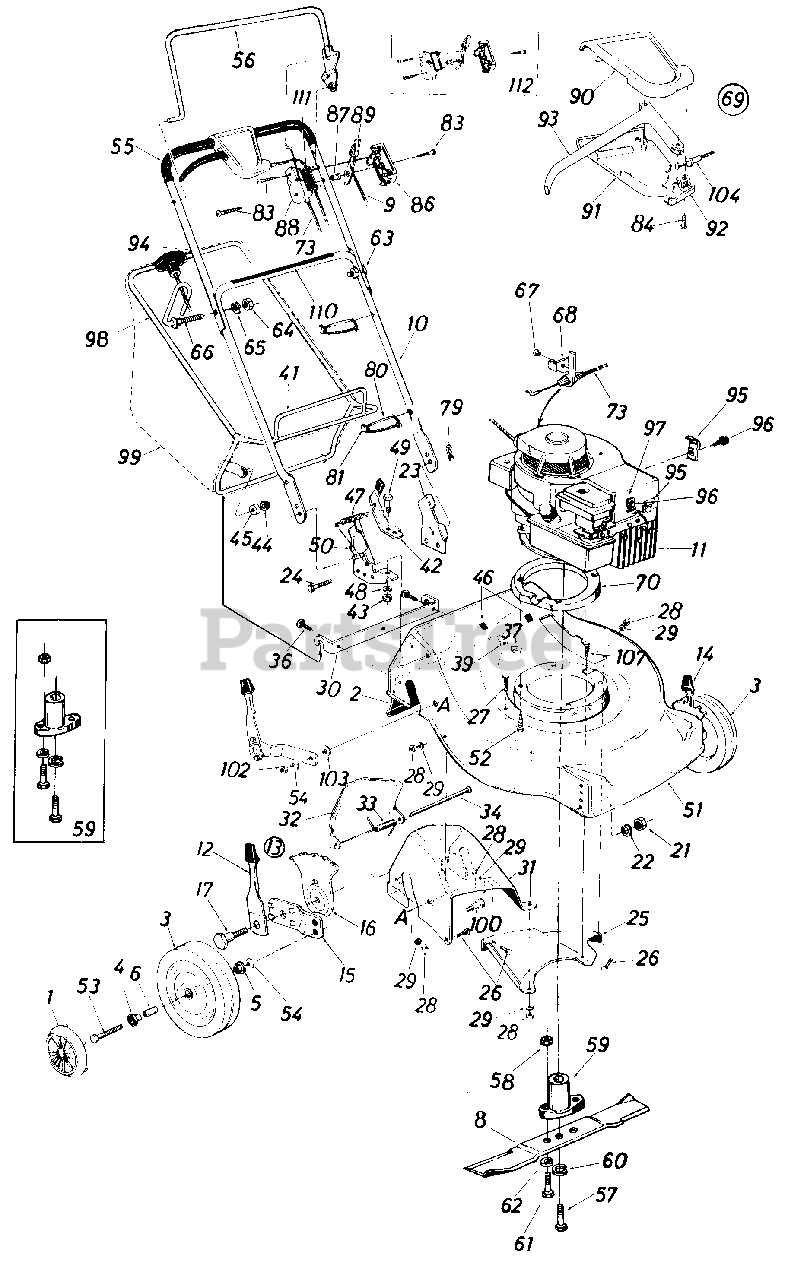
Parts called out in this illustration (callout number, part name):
1	Hub Cap
2	Rear Flap Ass'y.
3	Front Wheel Ass'y
4	Bearing
5	Bearing
6	Spacer
8	22" Blade
9	Throttle Control Wire-58"
10	Lower Handle
11	Engine
12	Spring Lever Ass'y.
13	Height Adj. Ass'y. Comp.-R.H.
14	Height Adj. Ass'y. Comp.-L.H.
15	Pivot Bar
16	Index Plate
17	Shld. Bolt .50" Dia. x .357
21	Hex Nut 3/8-16 Thd.*
22	Bell-Wash. .39" I.D. x 1.38"
23	Handle Bracket-L.H.
24	Hex Self-Tap Screw 1/4" x .62" Lg.
25	Rear Baffle-L.H.
26	Carriage Bolt 1/4-20 x .50"
27	Hex Bolt 1/4-20 x .88" Lg.*
28	Hex Nut 1/4-20 Thd.*
29	L-Wash. 1/4" I.D.*
30	Hitch Bracket
31	Rear Chute Baffle
32	Chute Door
33	Torsion Spring
34	Hinge Pin
36	Carr. Bolt 1/4-20 x .75" Lg.
37	Sems Nut 1/4-20 Thd.
39	Flat Wash. .285" I.D.
43	Hex Nut 5/16-18 Thd.*
44	Push Cap
45	Plastic Roller
47	Extension Spring
48	L-Wash. 5/16" I.D.*
49	Shoulder Bolt
50	Handle Bracket-R.H.
51	22" Deck Ass'y.
52	Hex Self-Tap Screw 3/8-16 x 1.00" Lg.
53	Axle Bolt
54	Belleville Washer
56	Control Handle
57	Hex Bolt 3/8-24 x 2.25"
58	Hex Nut 5/16-24 Thread
59	Blade Adapter Kit
60	L-Wash. 3/8" I.D.-H.D.
61	Hex Bolt 5/16-24 x 1.00"
62	L-Wash. 5/16" I.D.
63	Carr. Bolt 5/16-18 x 1.38"
64	Hex Nut 5/16-18 Thd.
65	L-Wash. 5/16 I.D.
66	Rope Guide Bolt
67	Pop Rivet
68	Control Bracket
69	Clutch Control Housing Comp.
70	Engine Mount Cover
73	Control Cable-43"
79	Cotter Pin 5/16
80	Cable Tie
81	Cable Anchor
83	Truss Mach. Scr. #12 x 1.5"
84	Self-Tap Scr. #10 x 1.0" Lg.
86	Control Panel Half
87	Control Disc Pin
88	Clutch Panel Half
89	Throttle Control Lever
90	Control Cover Half-Upper
91	Control Cover Half-Lower
92	Cable Mounting Cap
93	Control Lever
94	Upper Handle
95	Casing Clamp
96	Hex B-Tap Scr. #10 x .38"
97	Casing Clamp
98	Catcher Upper Frame
99	Grass Bag (without Flip Top)
100	Shoulder Bolt
102	Hex Jam Nut 3/8-16 Thd.
103	Belleville Washer
104	Clutch Cable-50"
107	Hex Self-Tap Screw 1/4-20 x.75" Lg.
110	Instruction Label-Handle
111	Control Label-Throttle
112	Control Housing Comp.
